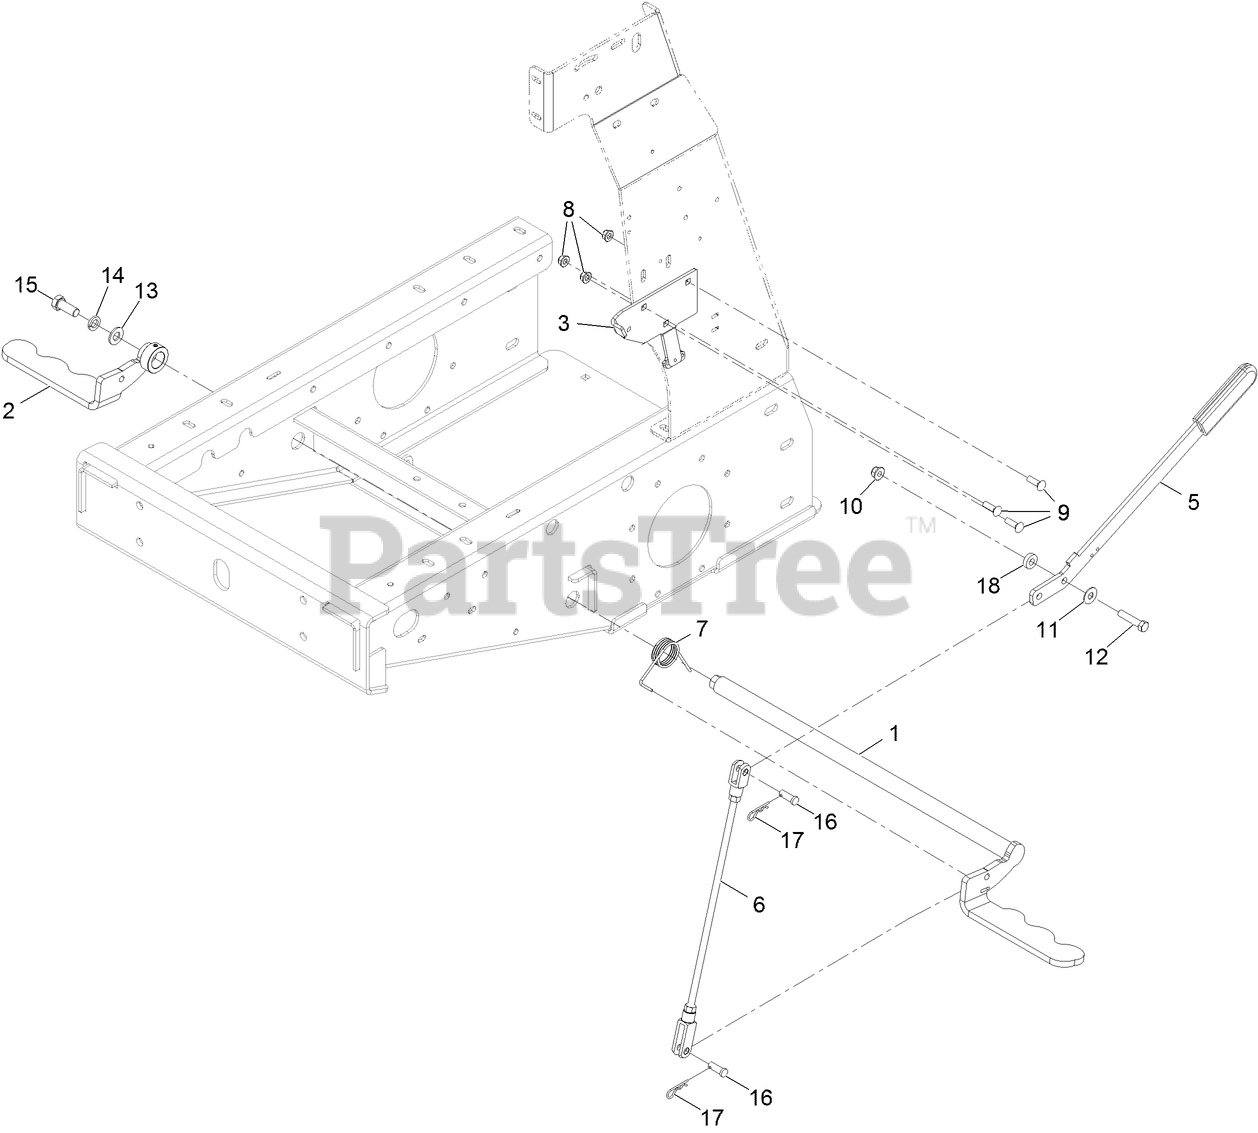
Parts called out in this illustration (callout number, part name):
1	Arm-Brake, Lt [black]
2	Arm-Brake, Rt [black]
3	Bracket-Handle, Brake
5	Handle-Brake
6	ASM, Rod-Brake
7	SPRING-TORSION
8	Nut-Hex Flange
9	Bolt,Carriage,5/16-18X1,ST/ST 18-8
10	NUT-HF, NI
11	WASHER-FLAT
12	SCREW-HH
13	WASHER-FLAT
14	WASHER-LOCK
15	Screw ( .50-20Unfx1.25 Grade 8]
16	PIN-CLEVIS
17	Pin-Hair
18	SPACER
